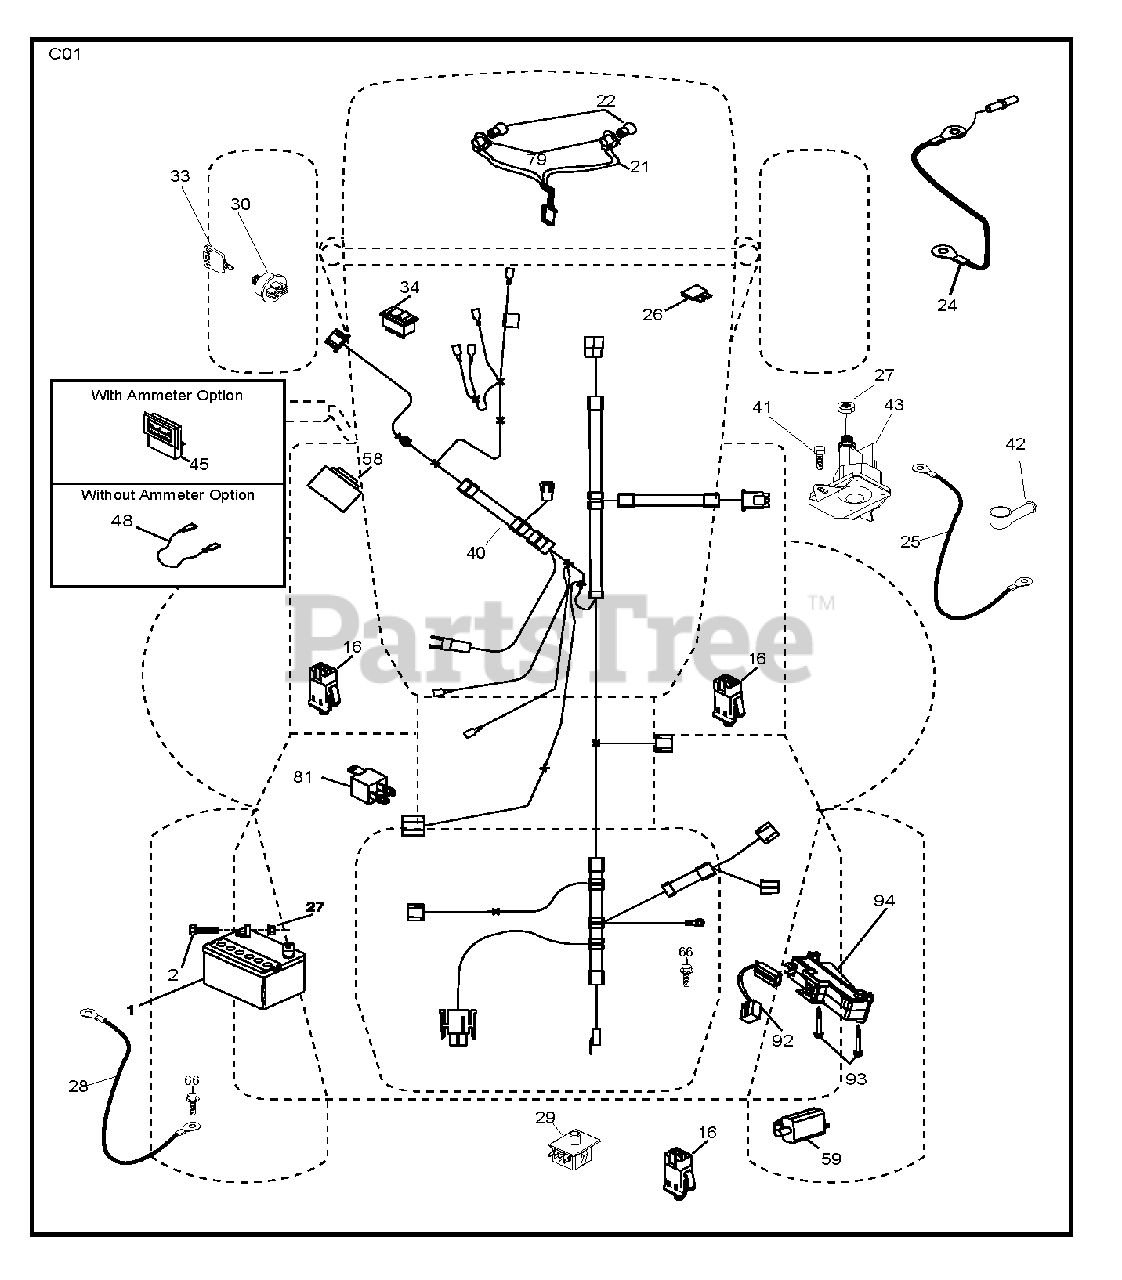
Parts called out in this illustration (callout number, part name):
1	REPL BY 532 12 38-99
16	SWITCH INTERLOOK PUSH-IN
21	HARNESS ASSY LIGHT
24	CABLE BATTERY 6 GA. 11" RED
25	CABLE BATTERY
27	NUT
29	SWITCH.SEAT.DP W/RAMPS
30	SWITCH.IGN.DELTA.W.LGH.ROS
33	KEY.CHAIN.BLISTER.PACK.GEN.INT
41	Hex Capscrew, 1/4-20
42	TERMINAL COVER
43	SOLENOID.W/BRASS.PLUNG
58	BUZZER
79	BULB HOLDER ASM.
92	HARNESS.PIGTAIL.CONSLE
93	SCREW.PLASTITE
94	MODULE.REVERSE.ROS
